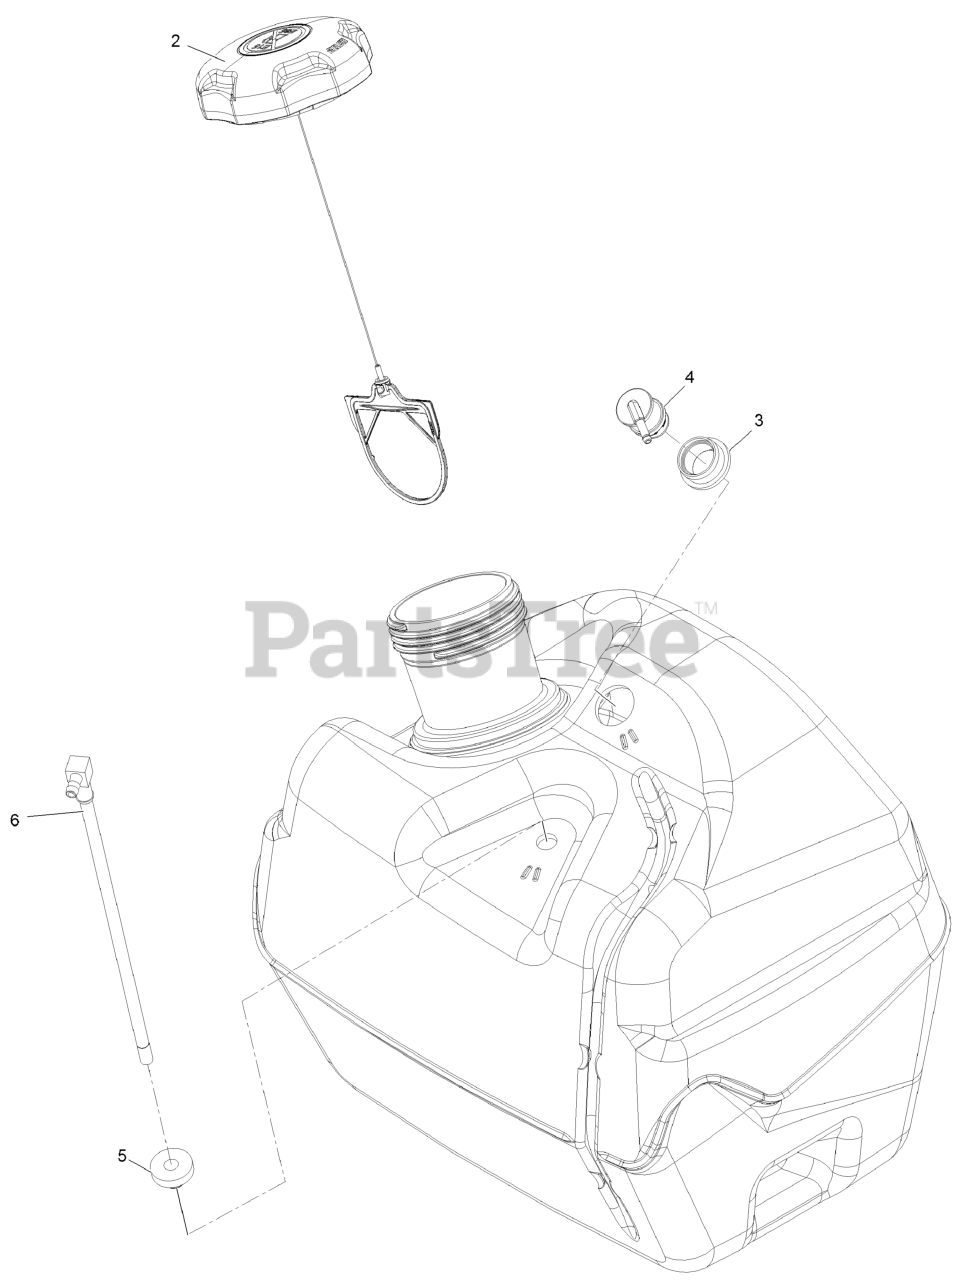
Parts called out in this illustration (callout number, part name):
2	CAP-FUEL, RATCHETING
3	GROMMET
4	VALVE-VENT, FUEL
5	BUSHING
6	FITTING, FUEL W/LINE AND SCREEN
